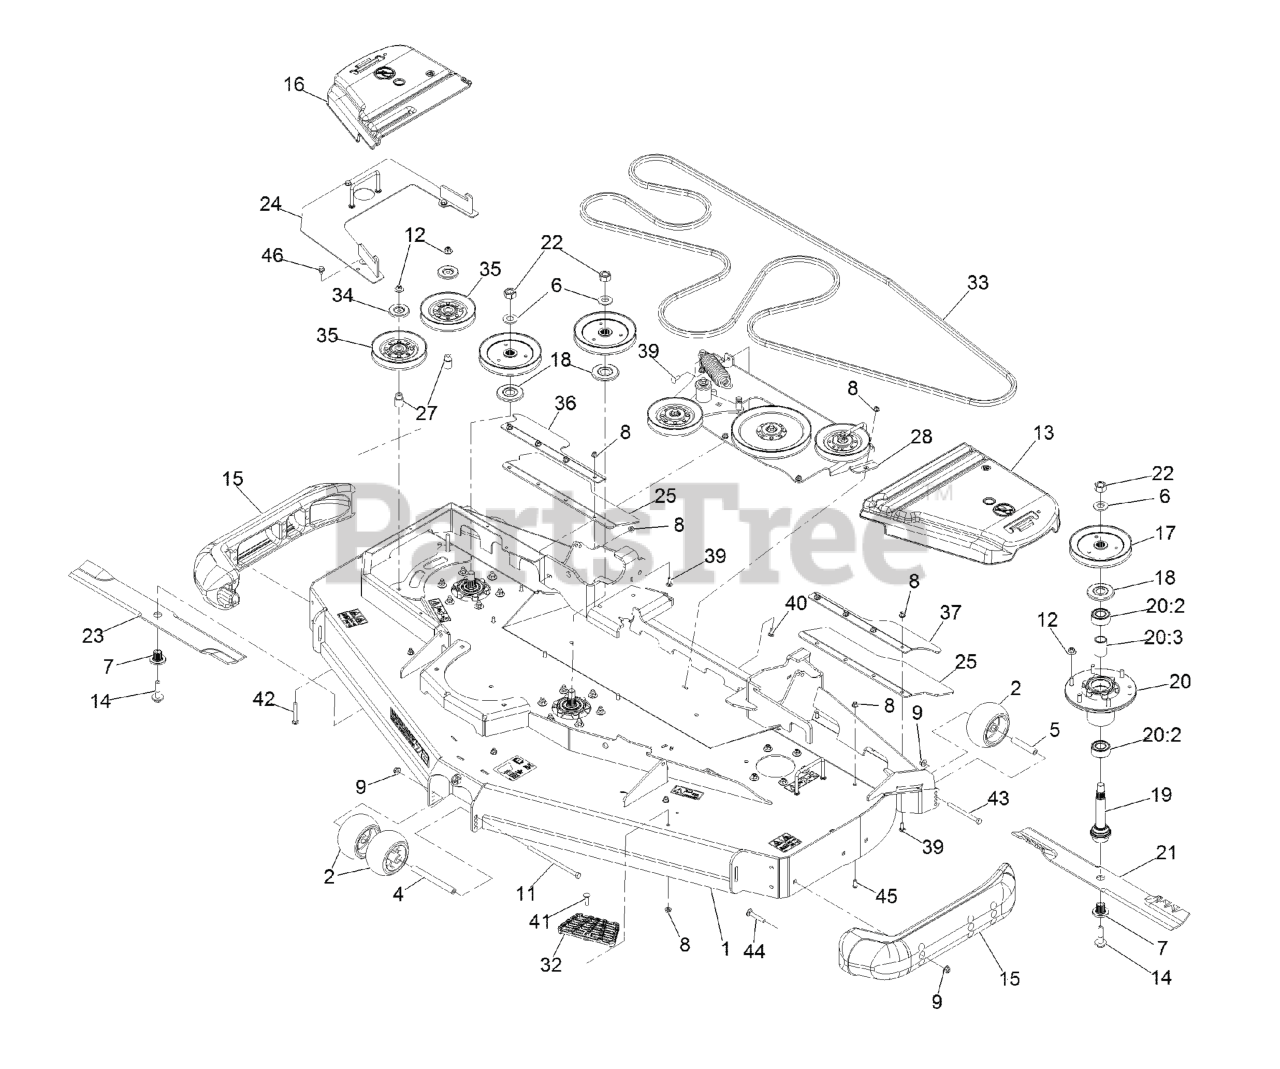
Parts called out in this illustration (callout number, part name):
1	DECK-RD72 W/DECALS
2	ROLLER-SCALP, ANTI
4	SPACER-WHEEL
5	TUBE-SPANNER
7	BUSHING,SPLINED
8	NUT-HF, NI
9	NUT-HF, NI
11	SCREW-HH
12	Nut-Nyloc 3/8-16 Flg
13	COVER-BELT, LH
14	SCREW,SEMS 1/2-20 X 2.19
15	SKID-BUMPER, DECK
16	COVER-BELT, RH
17	SHEAVE,BLADE DRIVE 6.50
18	GUARD-BEARING, TOP
19	ASM-SPINDLE AND SEAL
20	ASM-CUTTER HSG
20:2	BEARING-3205 TRASHGUARD
20:3	SPACER-BEARING
22	NUT-HEX
24	COVER-REVERSE DRIVE
25	GUARD-TIRE
27	STANDOFF-IDLER
28	Idler Mount ASM
32	STEP-DECK
33	BELT-BB
34	SHIELD-DUST
35	IDLER V
36	SUPPORT-FLAP, OUTER (RH)
37	SUPPORT-FLAP, OUTER (LH)
39	SCREW-CARR
40	SCREW-CARR
41	Bolt-Carriage 5/16-18 X 1 1/4
42	SCREW-CARR
43	SCREW-HH
44	Bolt-Carriage 3/8-16 X 2 1/4
45	SCREW-HSBH
